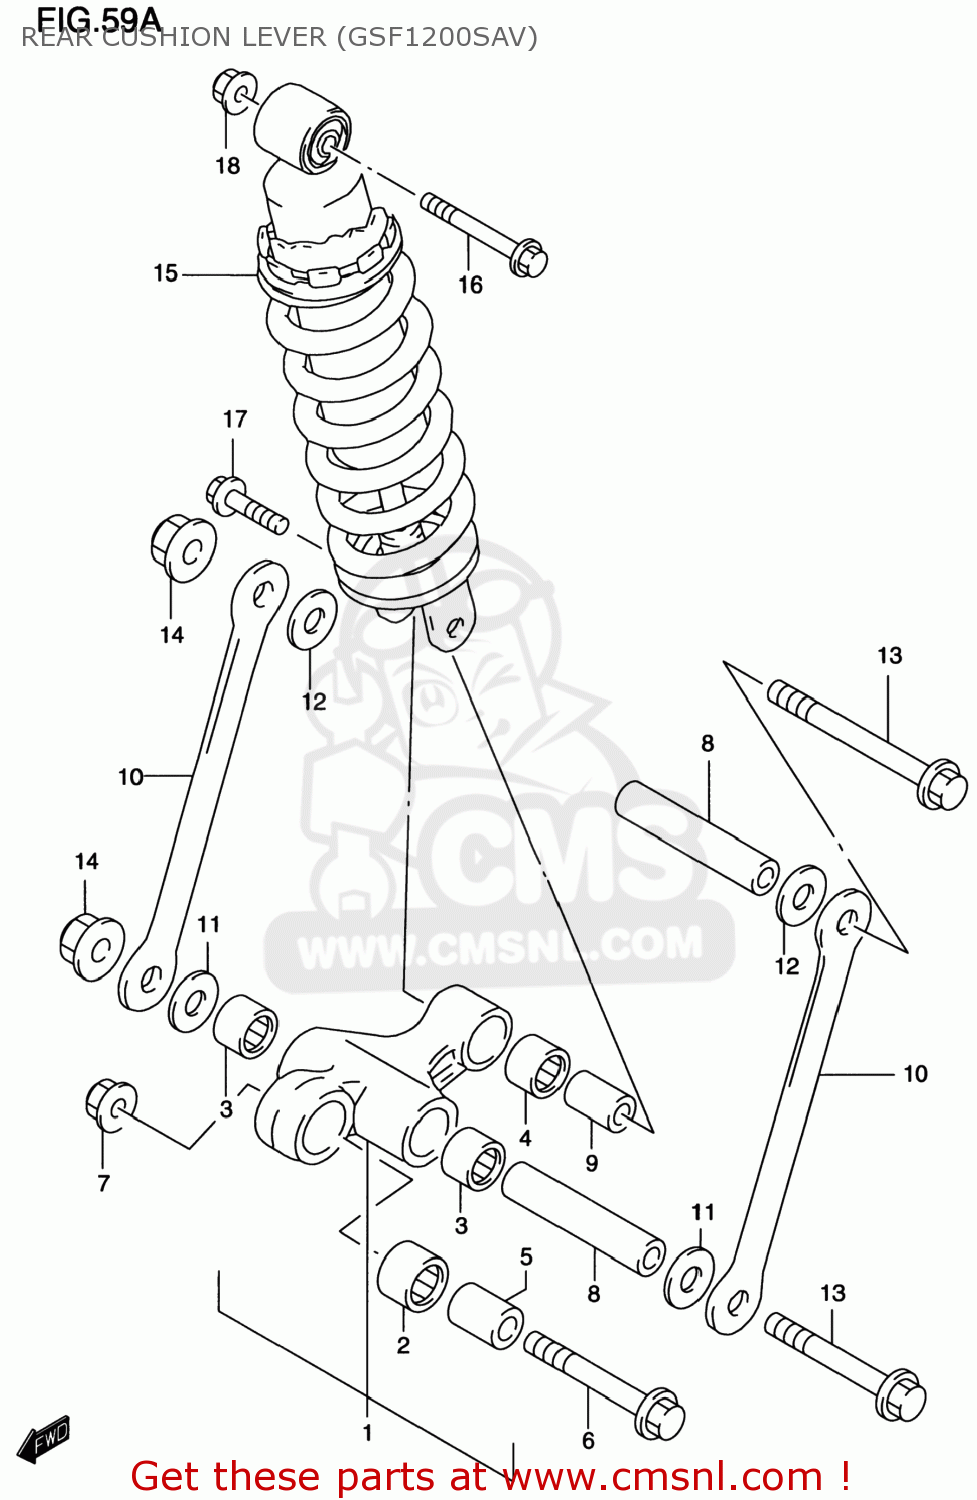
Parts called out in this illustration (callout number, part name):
1	LEVER SET,RR CUSHION
2	BEARING(20X27X26)
3	BEARING(17X24X25)
4	BEARING(17X24X26)
5	SPACER,RR CUSHION LEVER FR
6	BOLT,CUSHION LEVER FR
7	NUT 12MM
8	SPACER(12X17X85)
9	SPACER,RR CUSHION LEVER
10	ROD,RR CUSHION LEVER
11	WASHER(12X34X1)
12	WASHER,RR CUSH LVR CTR,L
13	BOLT(12X115)
14	NUT 12MM
15	ABSORBER ASSY,RR SHOCK
16	BOLT(10X50)
17	BOLT(10X44)
18	NUT
